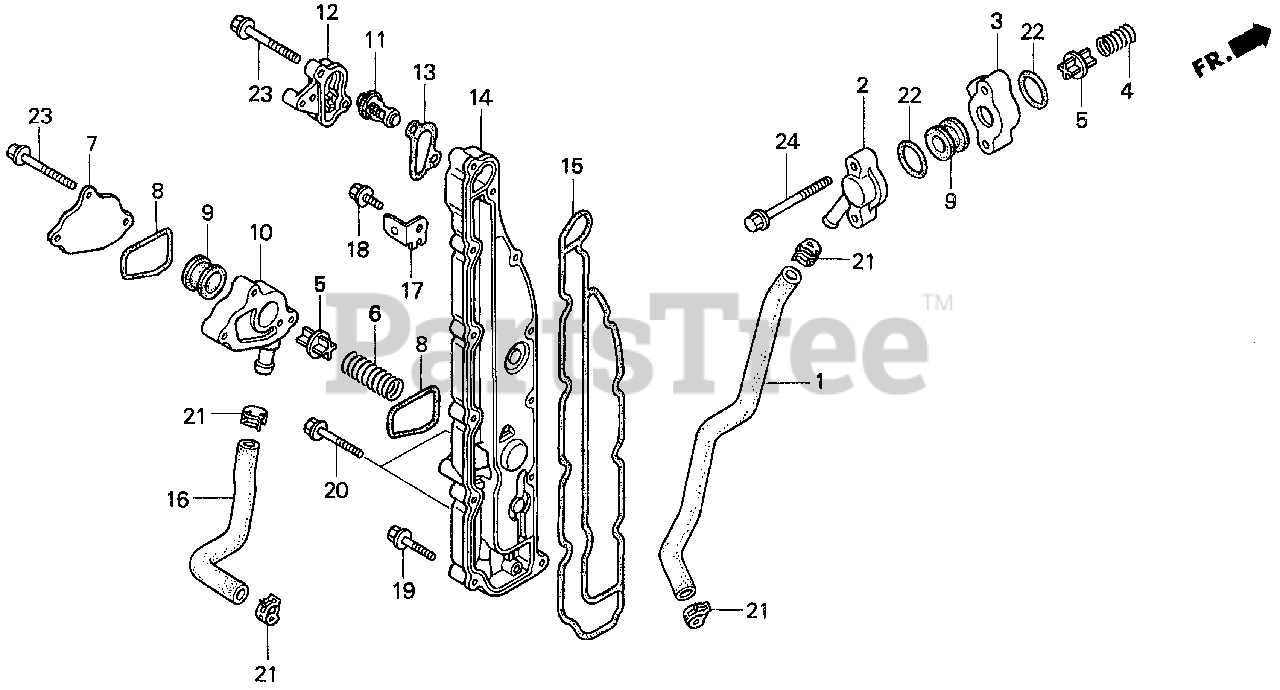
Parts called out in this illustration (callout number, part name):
2	COVER, FLUSH VALVE *NH8* (DARK GRAY)
3	SPACER, FLUSH VALVE *NH8* (DARK GRAY)
4	SPRING, FLUSH VALVE
5	VALVE, RELIEF
6	SPRING, RELIEF VALVE
7	COVER, RELIEF VALVE
8	GASKET, RELIEF VALVE COVER
9	GASKET, RELIEF VALVE
10	SPACER, RELIEF VALVE *NH8* (DARK GRAY)
11	THERMOSTAT ASSY. (72 DEGREES C)
12	COVER, THERMOSTAT *NH8* (DARK GRAY)
13	GASKET, THERMOSTAT COVER
14	COVER, WATER JACKET *NH8* (DARK GRAY)
15	GASKET, WATER JACKET COVER
17	STAY, IGNITION WIRE CLAMP
18	BOLT, FLANGE (6X12)
19	BOLT, FLANGE (6X25)
20	BOLT, FLANGE (6X32)
22	O-RING (31.5X2.4) (NOK)
22	O-RING (31.5X2.4) (ARAI)
23	BOLT, FLANGE (6X40)
24	BOLT, FLANGE (6X55)
